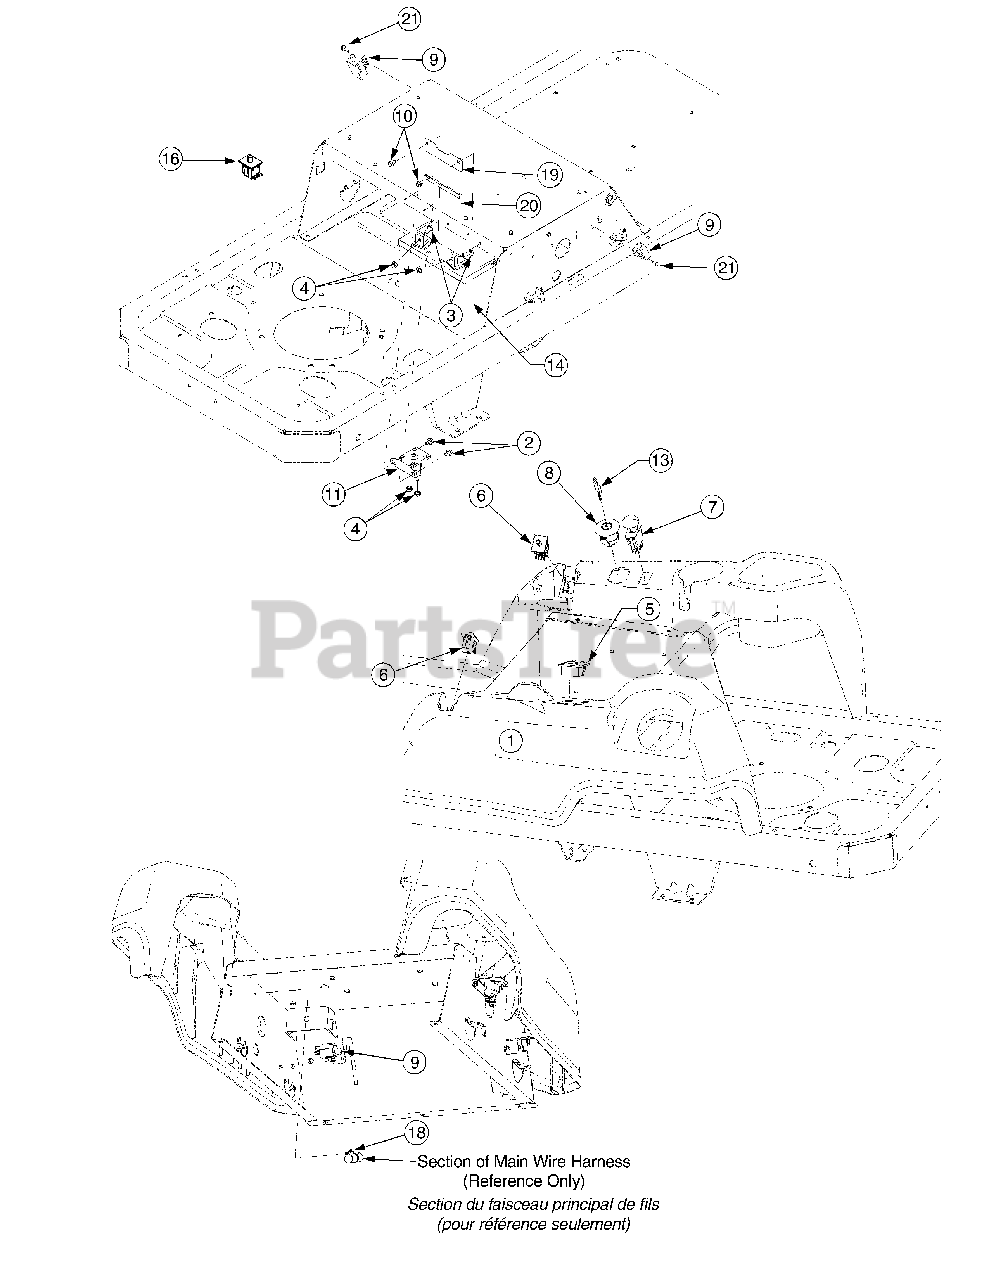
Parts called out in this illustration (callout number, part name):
1	Hex Wash HD AB S-Tapp Screw #8-.50
2	Hex Wash HD Tapp Screw 1/4-20 x .375
3	Hex Cap Bolt 1/4-20 x .75" Lg.
4	Sems Hex Nut 1/4-20
5	Meter, Indicator/Service Monitor
6	Switch, Dbl. Pole - Neutral
7	Switch, PTO
8	Switch, Ignition
9	Switch, Interlock, (NO-NC)
10	Hex Wash S-Tapp Screw 1/4-20 x .50
11	Solenoid
12	Seat Spring Switch
13	Key (Cub)
14	Battery 245 CCA (Dry)
16	Seat Switch
18	Cable Tie 19 x 8.39"
19	Bracket, Battery Hold down
20	Trim Strip 5" Lg.
21	Shoulder Screw #10-32 x .5
